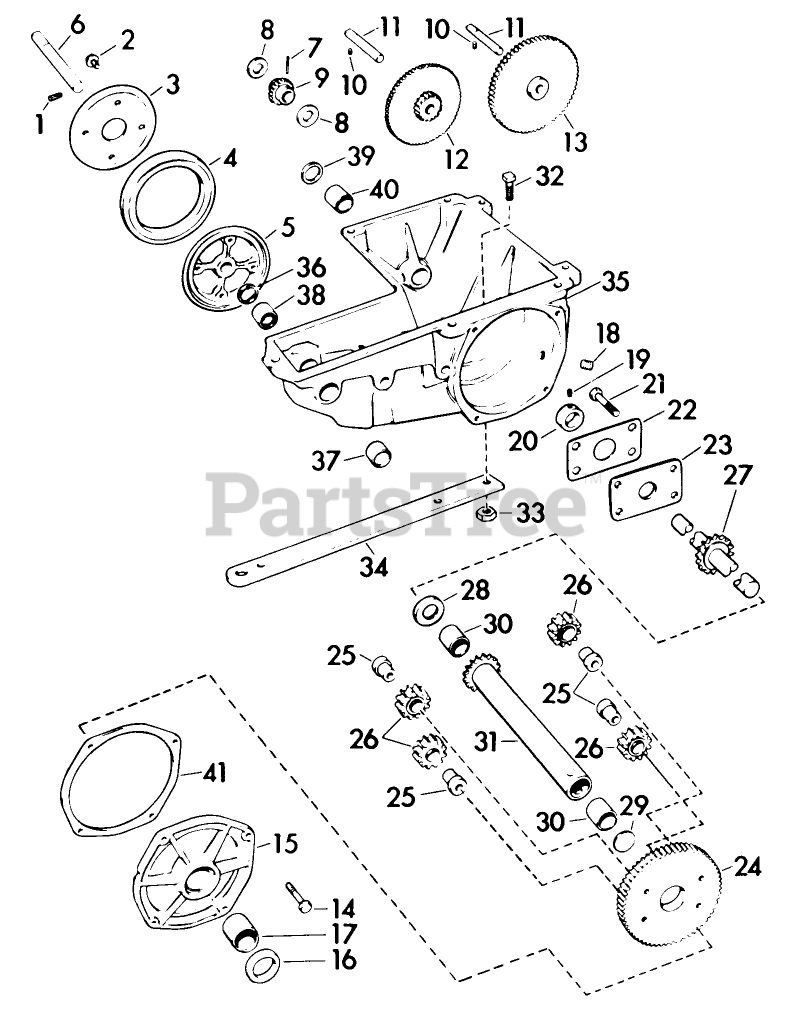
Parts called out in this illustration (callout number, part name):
1	Roll Pin
10	SET SCREW
21	Screw-Differential
24	Gear-Reduction (No. 3)
26	Gear-Planet, Differential
34	Bar-Draw
